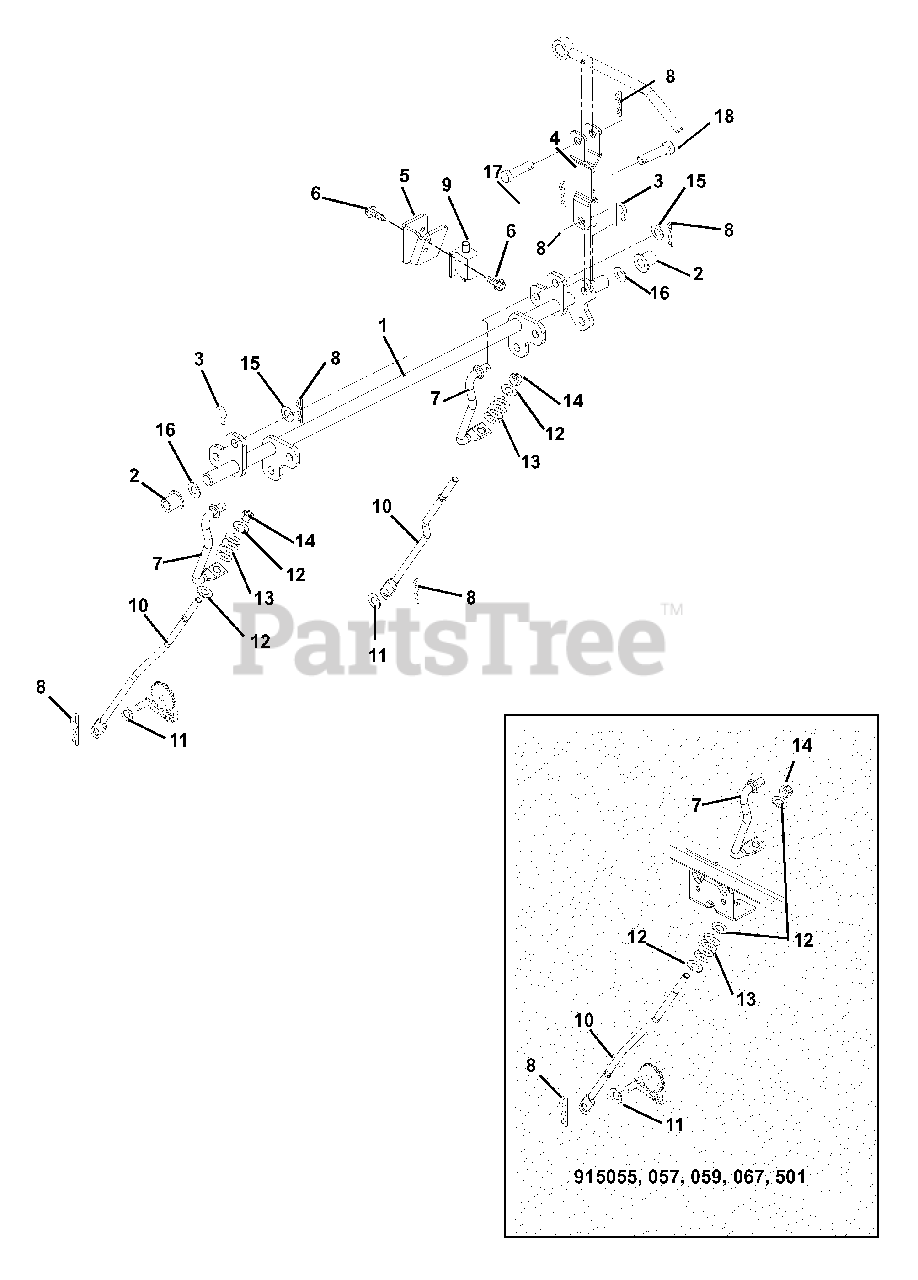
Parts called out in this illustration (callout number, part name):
1	WMT, BRAKE ROD
2	BSHG-FLG .630X1.000X.625 NY
3	PIN, SPRING CLIP
4	CLEVIS WELDMENT
5	BRACKET, BRAKE SWITCH
6	@SCR-TAP 10-24X.50 HWH TR YWZC
7	ROD-OVER CENTER
8	PIN-HAIR, ENDRIES #25 YWZC
9	SWITCH- DOUBLE POLE N.O./N.O.
10	ROD-PARK BRAKE EZT
11	WSHR-FL-STL .406X1.00X.188 YWZ
12	@WSHR-FL-STL.344X.688X.065YWZC
13	SG-COMP .063X.53X1.187
14	@NUT-LK-NYL .312-18 YWZC
15	@WSHR-FL-STL.406X.812X.065 YWZ
16	WSHR-FL-STL .627X.990X.032
17	PIN-CLEV .370X1.50
18	PIN-CLEV .375X.948 YWZC
